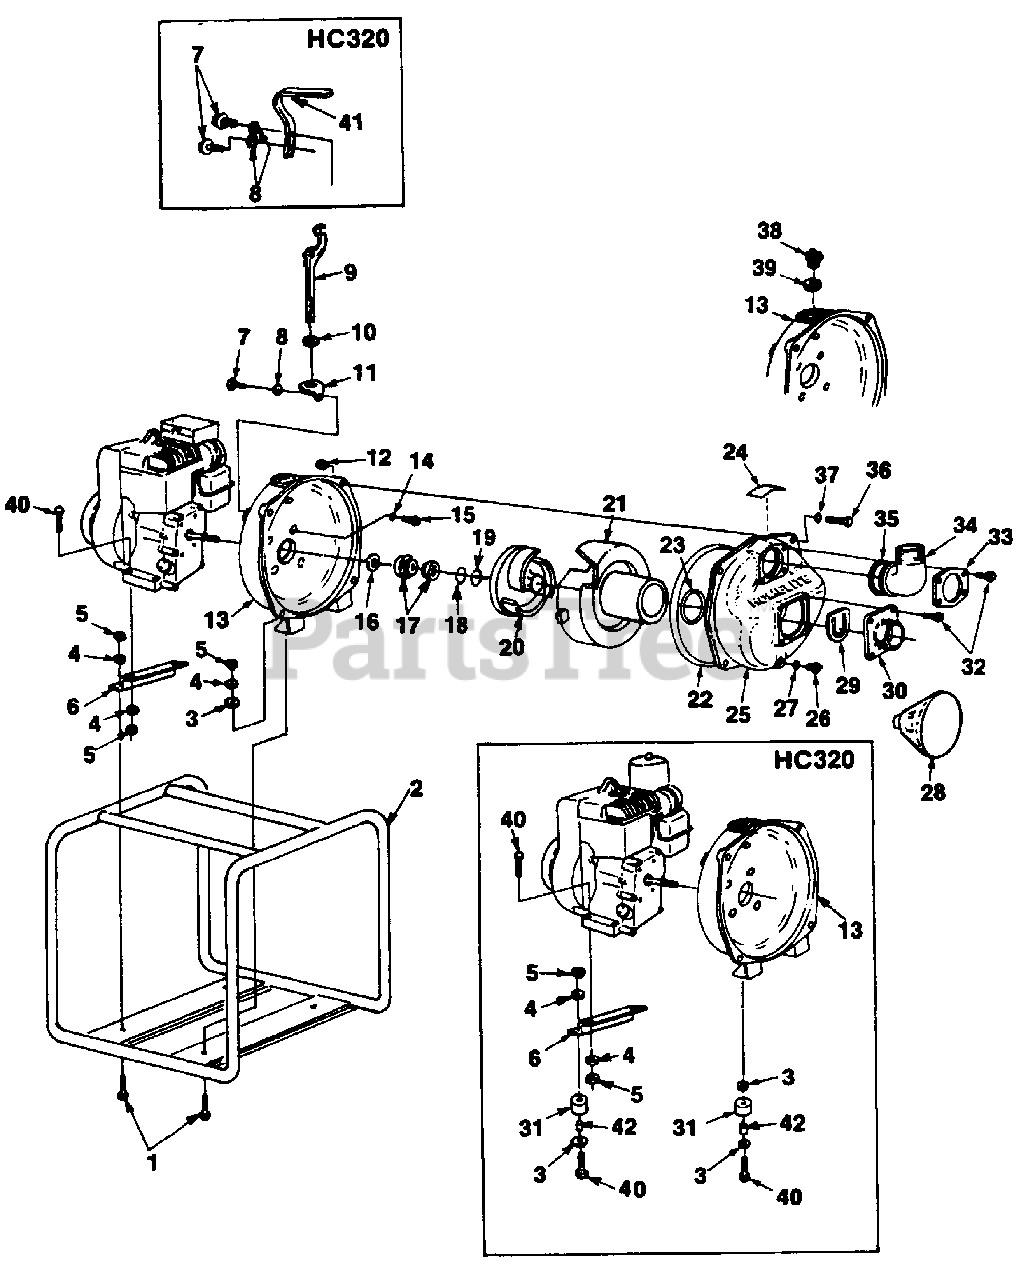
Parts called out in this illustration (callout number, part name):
3	WASHER- Flat (5/16")
4	WASHER- Lock (5/16")
5	NUT- Hex (5/16")
6	SUPPORT- Engine
7	SCREW- Tap hex hd. (1/2-13 x 1 3/4")
8	WASHER- Lock (1/2-13)
9	WRENCH- Spanner (2")
10	GROMMET
11	BRACKET- Spanner wrench
12	NUT- Hex (1/2-13)
13	CASING- Pump
14	WASHER- Sealing
15	SCREW- Mach. Hex
16	"O" RING
17	SEAL- Shaft
18	SHIM (.010")
19	SHIM (.020")
20	IMPELLER, 3 H.P.
21	DIFFUSER, 3 H.P.
22	"O" RING
23	RING- Square
24	LABEL- Warning
25	COVER- Suction
26	CAP- Drain & Filler
27	GASKET- Cap
28	STRAINER (2")
29	VALVE- Check
30	FITTING- Suction (2")
32	SCREW- Hex hd. (1/32-18 x 1")
33	CLAMP- Discharge
34	ELBOW- Discharge (2")
35	"O" RING
36	SCREW- Hex hd. (1/2-13 x 1 1/2")
37	WASHER- Lock (1/2")
38	PLUG- Filler
39	GASKET- Wing nut
40	SCREW- Cap hex hd. (1/32-18 x 1 1/2")
41	HANDLE- Carry
42	SPACER- Foot
